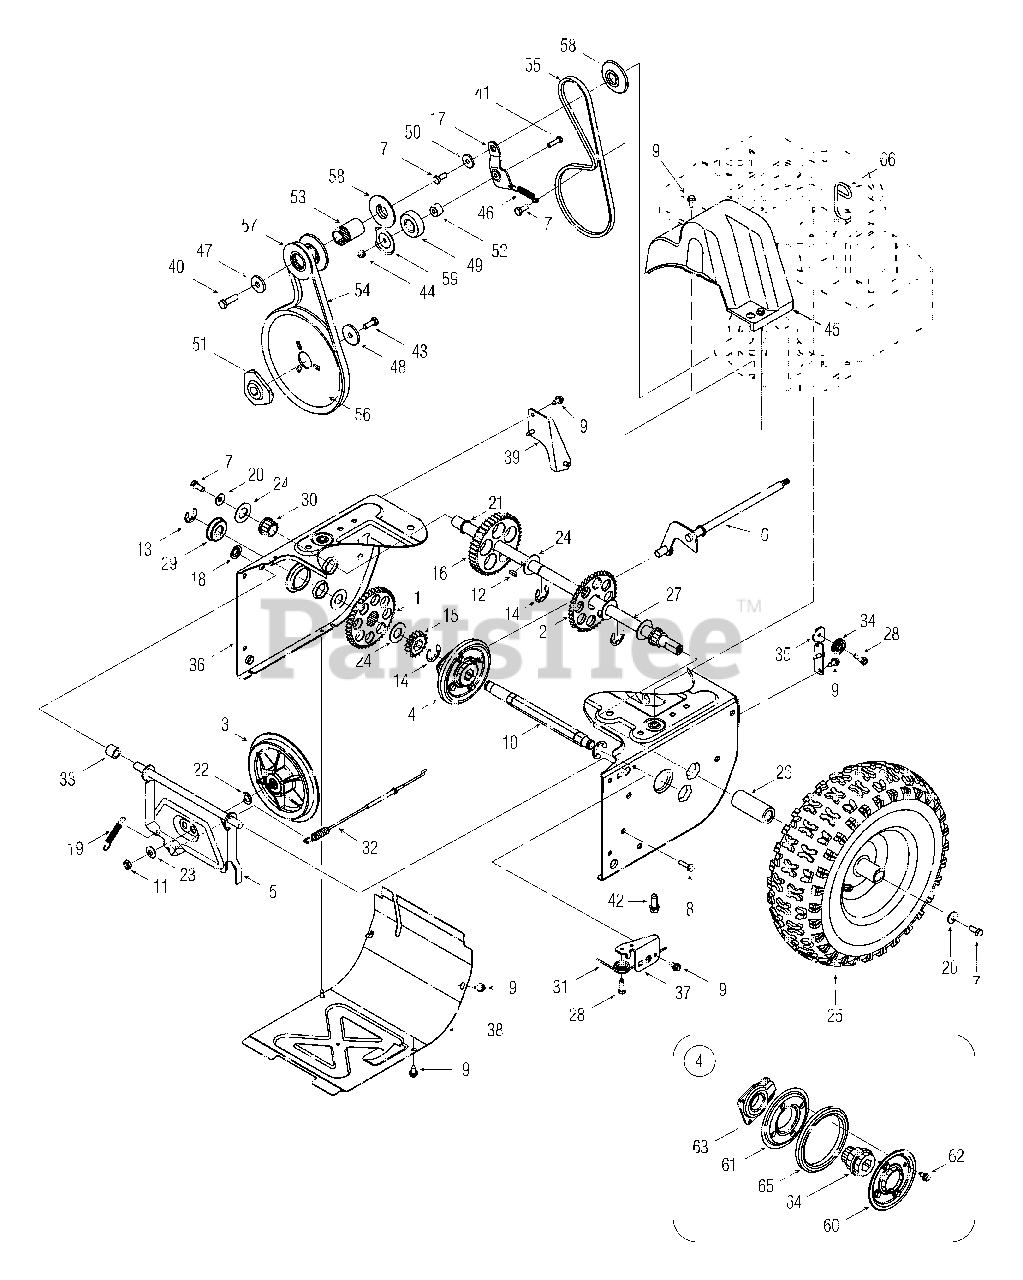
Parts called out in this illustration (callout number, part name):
1	Gear Assembly, 16/44T
2	Gear Assembly, 16/44T
3	Disc Assembly, Friction Wheel, .375
4	Wheel Assembly, Friction, 4.9 OD
7	Screw, 5/16-24 x .750, Gr5
8	Screw, 1/4-20 x 1.000
9	Screw, 1/4-20 x .625
10	Hex Shaft, Drive, .75
11	Nut, Jam, 3/8-24, Gr2
12	Key, Hi-pro 3/16 x 5/8
13	Ring, E Type, .750
14	Ring, E-Type, .875
15	Pinion, 16T
16	Gear, 44T
19	Extension Spring
20	Washer, Bell, .340 x .872 x .060
21	Washer, Flat, .75 x 1.00 x .060
22	Washer, Flat, .406 x .875 x .059
23	Washer, Bell, .375 x .870 x .063
24	Washer, Flat, .793 x 1.24 x .060
25	Wheel Assembly Complete, Wheel Size 13 x 4
25	Wheel Assembly Complete, Wheel Size 15 x 5
26	Spacer, 1.25 OD x .75 ID x 3.00
27	Axle, .75 x 22
28	Screw, 1/4-28 x .375
29	Bearing, Ball, 17 x 40 x 12
30	Bearing, Hex Flange x .75 ID
31	Cable, Auger, 44.75
32	Cable, Drive, 41.75
33	Spacer, .508 ID x .75 OD x .68
34	Roller, Cable
41	Screw, 1/4-20 x 1.00, Gr5
42	Screw, Sems, 3/8-16 x 1.00
43	Screw, 5/16-24 x .875, Gr8
44	Nut, Flange Lock, Nylon, 1/4-20, Gr F
45	Cover, Belt
46	Spring, Extension, .38 OD x 2.68
47	Washer, Flat, .406 x 1.25 x.157
48	Washer, Flat, .34 x 1.50 x .150
49	Bearing, Ball, 20 x 47 x 14
50	Shoulder Spacer
51	Pulley, Adapter, .75 Dia.
52	Spacer, .777 OD x .260 ID x.550
53	Spacer, .875 ID x 1.185 OD
54	V-Belt, 1/2"
55	V-Belt, 3/8"
56	Pulley, Auger, 8.1 x .50
57	Pulley, Half, 2.600 OD
58	Pulley, Half, 2.2 OD
59	Washer, Bearing, 2.12 OD x .255 ID
60	Plate, Friction, 12 Pt 4.60 Dia
61	Plate, Friction, Extrs, 12 Pt 4.60 Dia
62	Screw, Self-tapping, 1/4-14 x 0.625
63	Bearing Assembly, Friction Wheel
64	Hub, Friction Wheel
65	Friction Wheel Rubber, 4.875 OD
66	Guide, Cable
